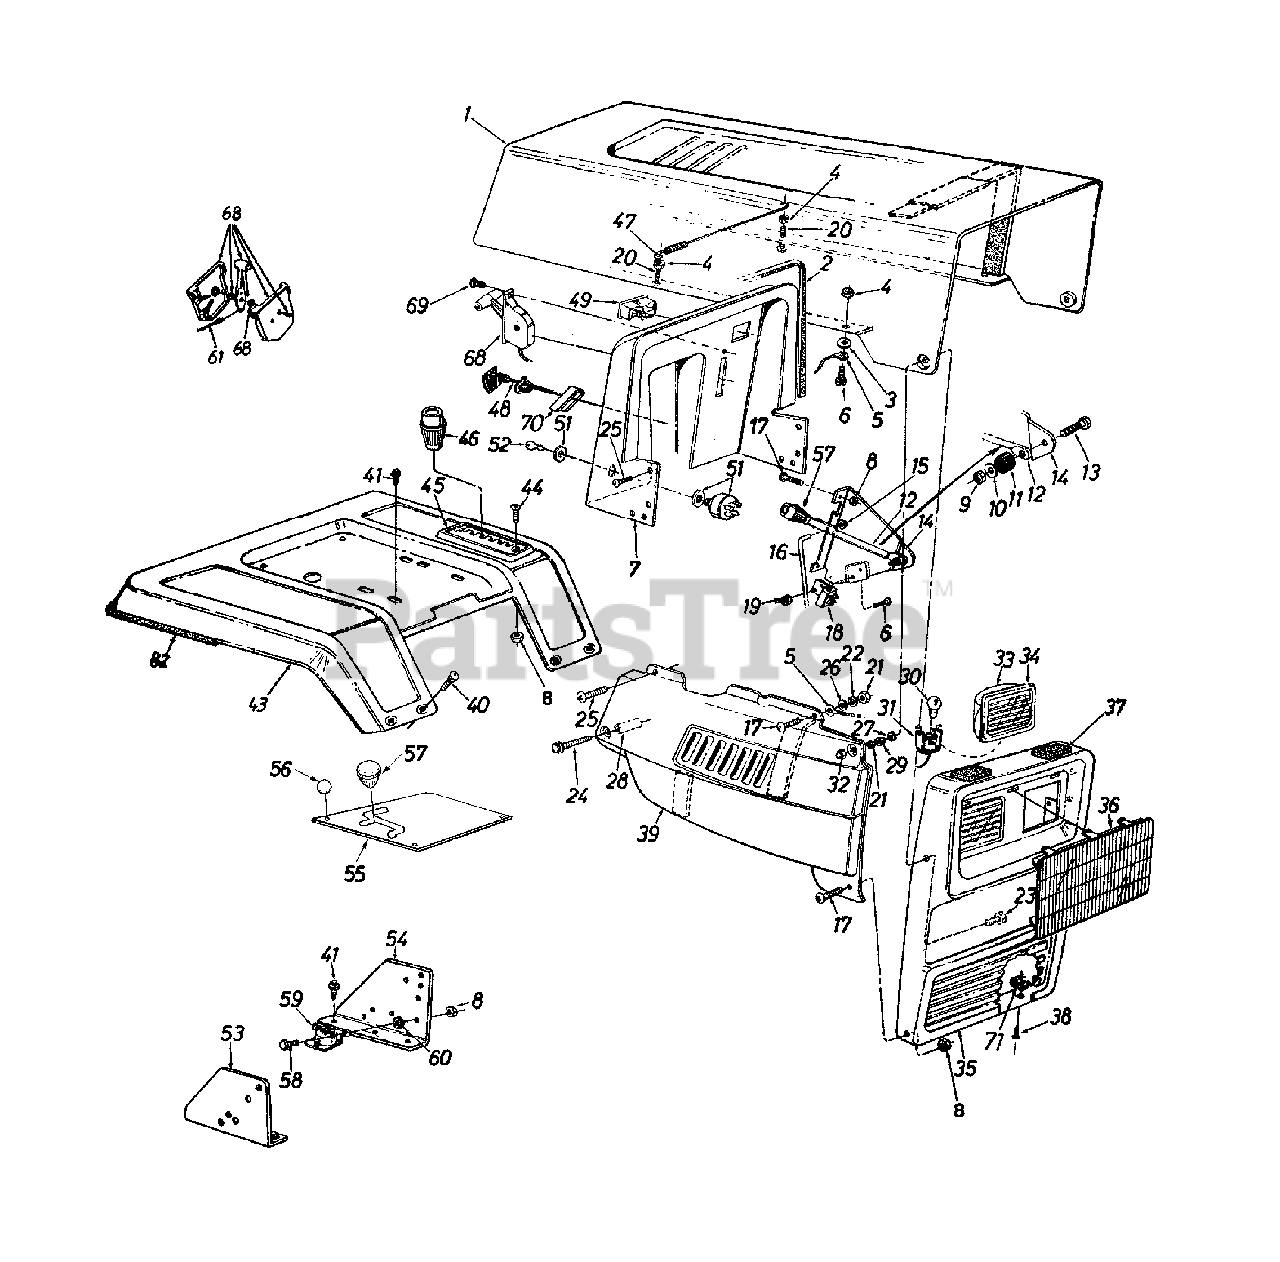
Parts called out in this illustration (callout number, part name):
3	Fl-Wash. .188" I.D. x .41" O.D.
4	Hex Sems Nut #10-24 Thd.
5	Hood Stop
6	Truss Mach. Scr. #10-24 x .5" Lg.
9	Hex L-Nut 1/4-20 Thd.
10	Fl-Wash. .281" I.D. x .73" O.D.
11	Rubber Washer
12	PTO Lever
13	Hex Bolt 1/4-20 x 1.25" Lg.
16	Deck Control Rod
17	Truss Mach. Scr. 1/4-20 x .5" Lg.
18	Safety Switch
19	Hex Sems Nut #10-24 Thd.
20	Hex Bolt 10-24 x 1.0" Lg.
21	Hex Nut 1/4-20 Thd.
22	L-Wash. 1/4" I.D.
23	Hex Bolt 1/4-20 x .88" Lg.
24	Hex Wash. TT-Tap Scr. 1/4-20 x 1.75" Lg.
25	Hex TT-Tap Scr. 1/4-20 x .75" Lg.
26	Fl-Wash. .25" I.D. x .62"
27	Spr. Wash. .39" I.D. x .62"
28	Spacer .26" I.D. x .375"
29	Shld. Spacer .375" Dia. x .125"Lg.
30	Lamp
31	Socket
32	Acorn Nut 1/4-20 Thd.
33	Headlight Housing
34	Headlight Lens
37	Foam Strip
38	Hex Bolt 5/16-18 x .75" Lg.
41	Hex Wash. AB-Tap Scr. 5/16 x .75" Lg.
45	6-Speed Selector Plate (828)
46	Shift Knob
47	Hood Spring
48	Choke Control 46" Lg.
49	Ammeter
51	Ignition Switch
52	Ignition Key
57	Knob-Blade Clutch
58	Hex Bolt 1/4-20 x .5" Lg.
59	Solenoid
60	Ext. L-Wash. 1/4" I.D.
61	Throttle Wire 35" Lg.
68	Throttle Control Box Ass'y.
69	Truss Mach. AB-Tap Scr. #10 x .5" Lg.
70	Retainer Clip
71	U-Nut 5/16-18 Thd.
82	Trim Strip 81" Lg.
